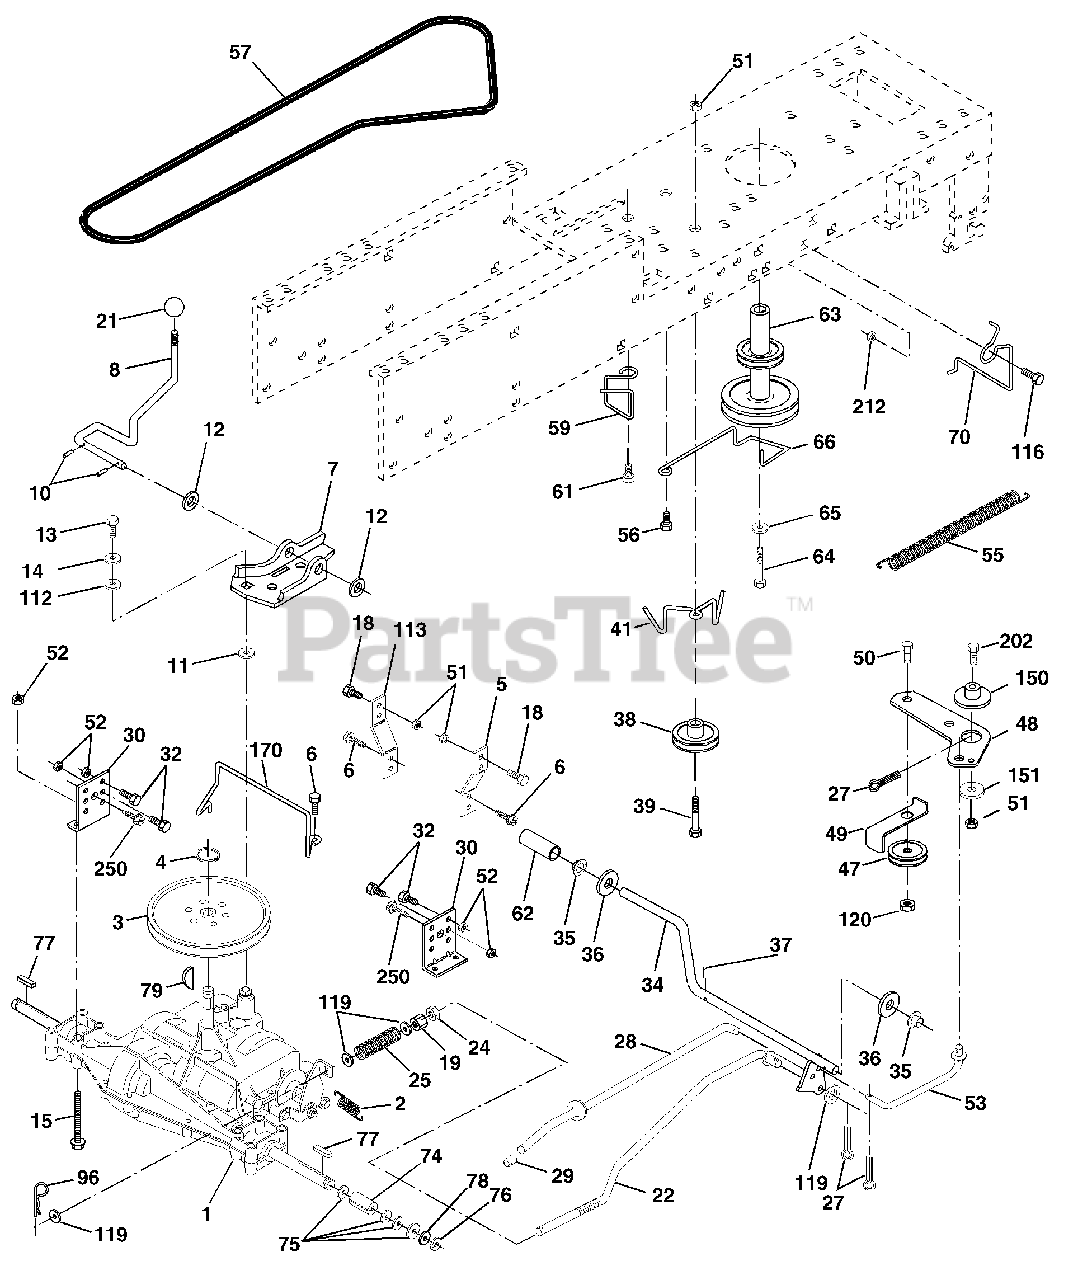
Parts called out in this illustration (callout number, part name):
2	Spring Return Brake T/a Zinc
3	Pulley Transaxle 18/20" tires
4	Ring Retainer #5100-62
5	Strap Torque 30 Degrees
6	Screw 5/16-18 x 3/4
7	Bracket Saddle Shift T/a
8	Rod Shf Sdl LY/YT Str Blk
10	Pin Cotter 1/8 x 1 Cad
11	Washer Plate 388 Sq Hole
12	Washer 15/32 x 3/4 x 16ga
13	Bolt 1/4-28unf Gr8 W/Patch
14	Washer Lock Hvy Helical 1/4
15	Bolt Hex Flghd 5/16-18 x Gr. 5
18	Bolt Fin Hex 3/8-16 UNC x 1 Gr. 5
19	Nut Lock Hex W/Ins. 3/8-16 Unc
21	Knob Rd 1/2-13 Plstc Thds
22	Rod Brake Blk Zinc 26 840
24	Nut Hex Jam 3/8-16 Unc
25	Spring Rod Brake 2 00 Zinc
27	Pin Cotter 1/8 x 3/4 Cad
28	Rod Brake Parking Lt/Yt
29	Cap Brake Parking
30	Bracket Mtg Transaxle
32	Bolt Hex Hd 5/16-18unc x 3/4
34	Shaft Asm Pedal Foot Nibbed
35	Bearing Nylon Blk 629 Id
36	Washer 21/32 x 1 x 16 Ga
37	Pin Roll 3/16 x 1"
38	Pulley Composite Flat
39	Bolt Fin Hex 3/8-16 UNC x 3 Gr. 5
41	Keeper Belt Idler
47	Pulley Idler V Groove Plastic
48	Bellcrank Asm. Clutch
49	Retainer Belt Style Spring
50	Bolt Hex Hd 3/8-16unc x1-1/2
51	Nut Crownlock 3/8-16 UNC
52	Nut Crown Lock 5/16-18
53	Link Clutch 7 66
55	Spring Return Clutch 6 75
56	Screw 3/8-16 x 1-1/4
57	V-Belt Gd Drive 9530
59	Keeper Belt Centerspan
61	Screw 3/8-16 x .875
62	Cover Pedal Blk Round
63	Pulley Eng Cl Cable
64	Bolt Hex 7/16-20 x 4 Gr 5
65	Washer Lock Hlcl Spr 7/16
66	Keeper Belt Engine FP
70	Guide Belt Mower Drive RH
74	Spacer Axle
75	Washer 25/32 x 1-1/4 x 16 Ga
76	E-ring #5133-75
77	Key Square 2 0 x 1845/1865
78	Washer 25/32 x 1-5/8 x 16 Ga
79	Key Woodruff #9 3/16 x 3/4
96	Retainer Spring 1
112	Washer 9/32 x 3/4 x 10 Ga
113	Strap Torque LH LT
116	Bolt 3/8-16 x 1
119	Washer 13/32 x 5/8 x 16 Ga
120	Nut Lock Flg 3/8-16
150	Spacer Retainer
151	Washer 13/32 x 2 x 10 Ga.
170	Keeper Belt Transaxle Gear
202	Bolt Carr. Sh 3/8-16 x 1-3/4 Gr. 5
212	Nut Hex Flange Lock
250	Screw 3/8-16 x 3/4
